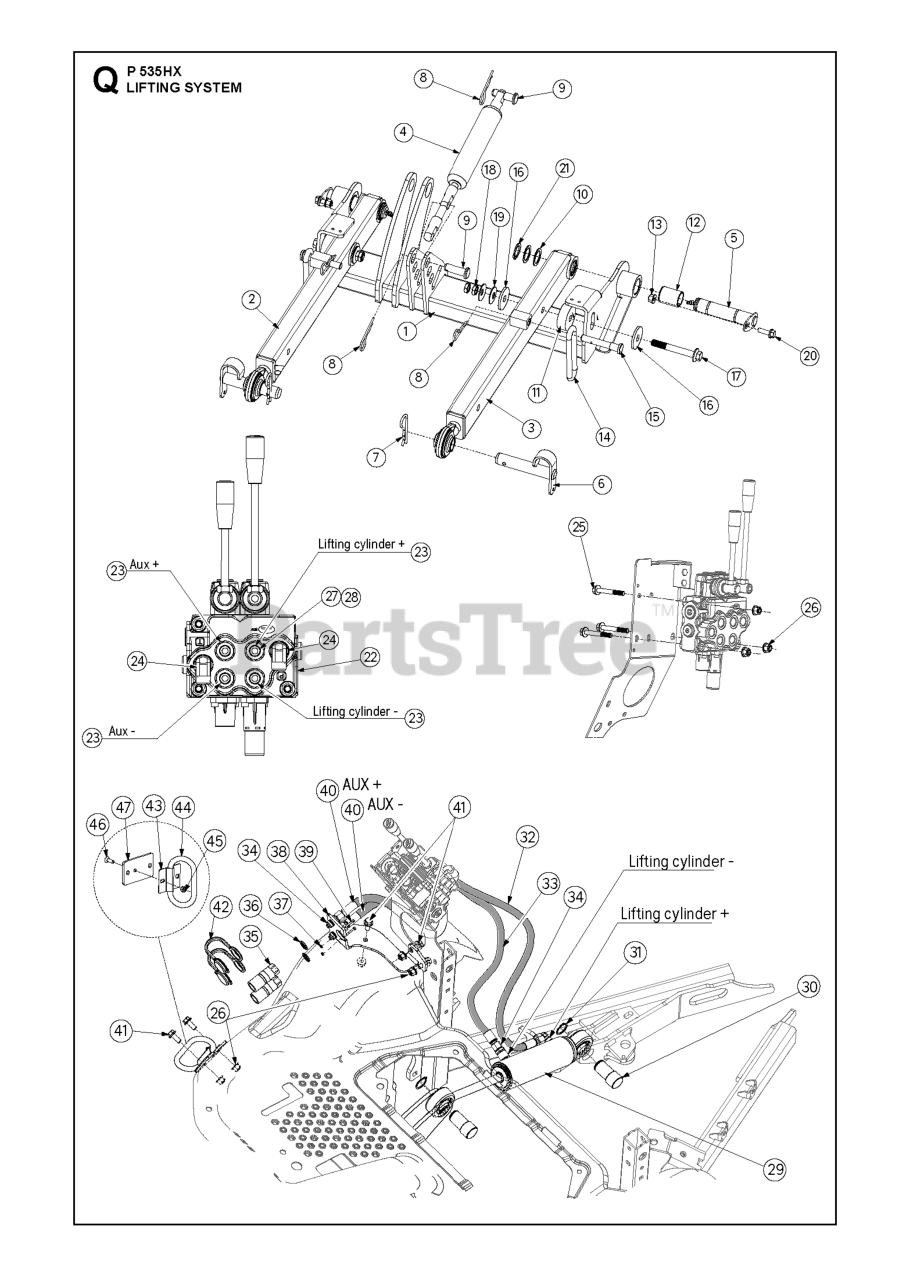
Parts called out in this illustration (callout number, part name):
6	Cotter Pins
9	CLEVIS PIN
13	NUT FLANGE
18	NUT HEXAGON THIN ISO 4035 M12
20	BOLT
26	NUT FLANGE
31	RETAINING RING SGA 25
37	NUT M6M M3
